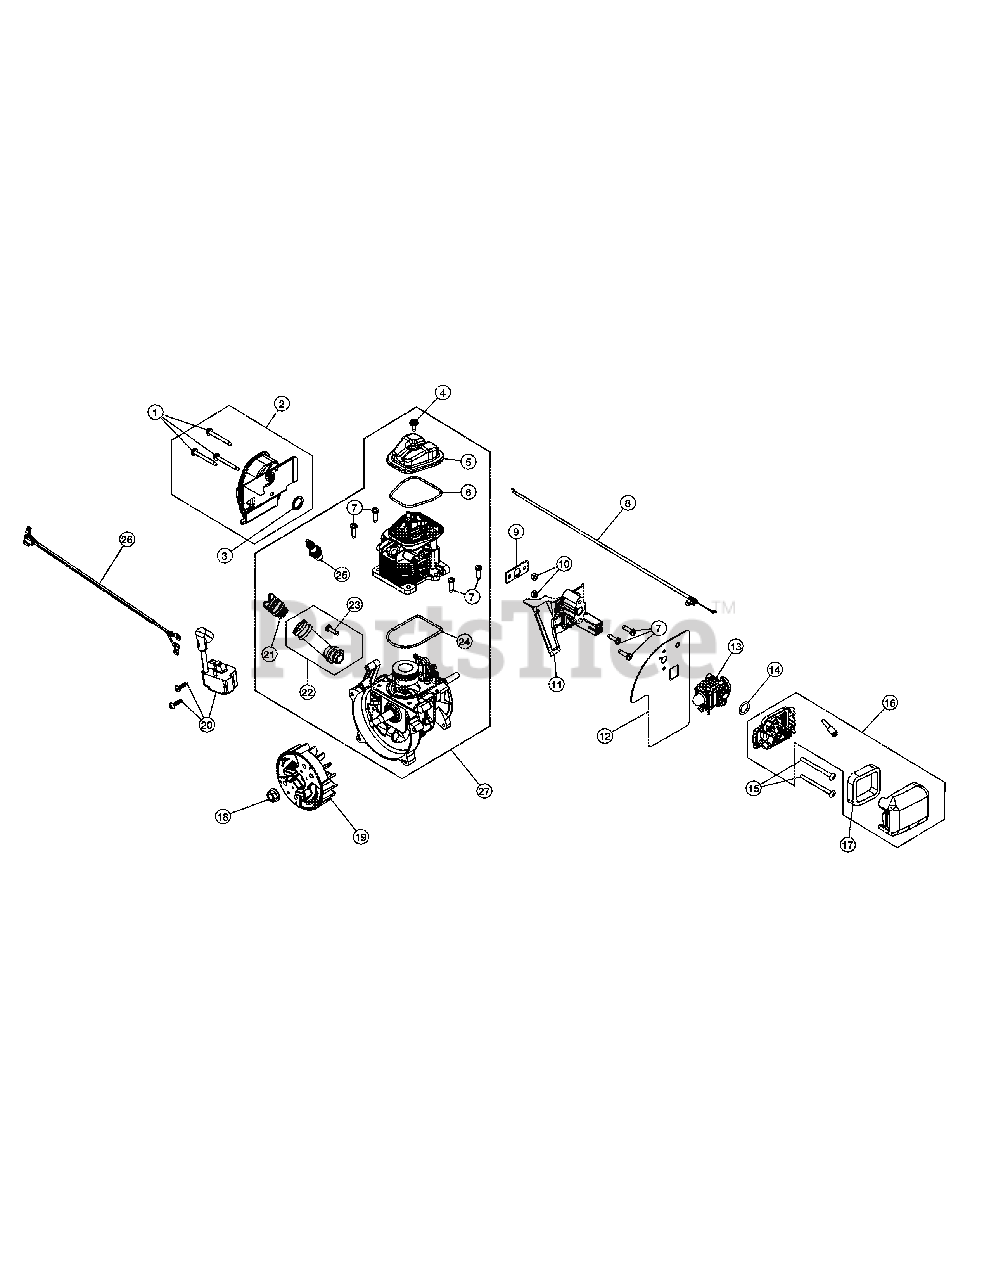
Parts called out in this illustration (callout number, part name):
1	Muffler Screws
2	Muffler Assembly (Incl. 1 & 3)
3	Muffler Gasket
5	Rocker Cover
7	Screw
8	Throttle Cable
9	Insulator Gasket
12	Carburetor Gasket
13	Carburetor
14	Carburetor O-Ring
16	Air Cleaner Assembly (Incl. 17)
19	Flywheel Asssembly
21	Oil Plug
22	Oil Fill Tube (Incl. 23)
25	Spark Plug
27	Short Block Assembly (Incl. 4-7 & 21-25)
